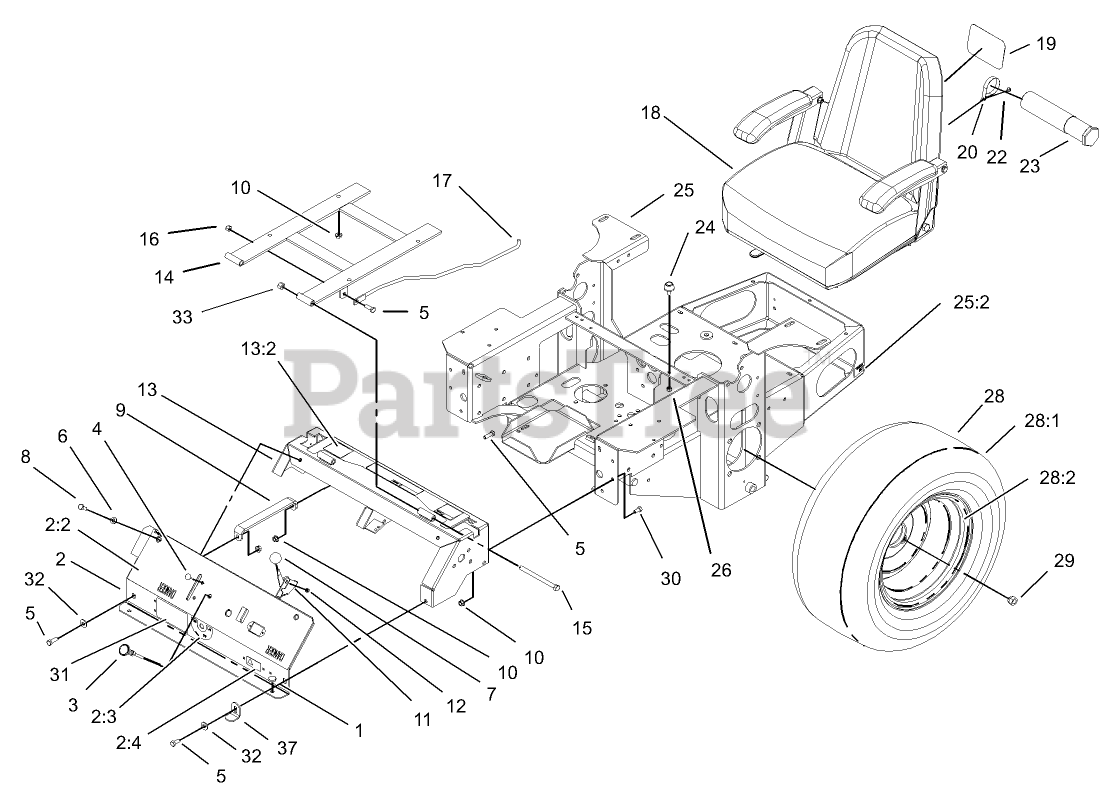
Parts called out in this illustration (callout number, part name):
1	BUMPER
2	CONTROL PANEL ASM
2:2	DECAL-PANEL, CONTROL
2:3	DECAL-VALVE, FUEL
2:4	DECAL-PROTECTION, EAR
3	CONTROL-CHOKE
4	BOLT-CARR
5	SCREW-HH
6	WASHER-PLAIN
7	KNOB-BALL
8	SCREW-HH
9	BRACKET
10	NUT-HF
11	THROTTLE CABLE ASM
12	NUT-LOCK, NI
13	CONSOLE
13:2	DECAL-CONTROL, MOTION
13:3	DECAL-BATTERY
14	FRAME-SEAT
15	SCREW-HH
16	NUT-LOCK, NI
17	ROD-RETAINER, SEAT
18	SEAT ASM
19	DECAL
20	CLAMP-R
22	SCREW-HWHTF
23	TUBE-MANUAL
24	BUMPER
25	Main Frame ASM
25:2	DECAL-SURFACE, HOT
25:3	Decal-Release, Drive
26	NUT-LOCK, NI
28	WHEEL AND TIRE ASM
28:1	TIRE
29	NUT-LUG
30	SCREW-HH
31	DECAL-Z147
32	WASHER-FLAT
33	NUT-LOCK, NI
37	STOP-COVER
